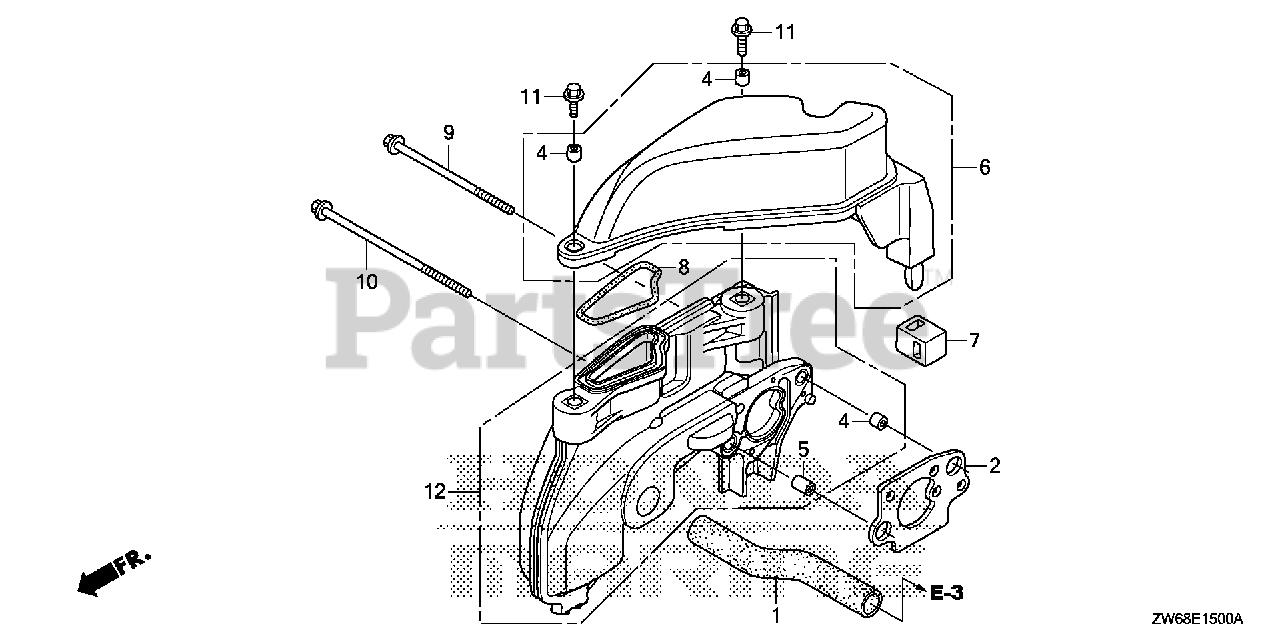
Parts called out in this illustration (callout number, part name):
1	TUBE, BREATHER
2	GASKET, AIR GUIDE
3	GUIDE ASSY., AIR
4	COLLAR, DISTANCE
5	COLLAR, DISTANCE (14MM)
6	CASE, MUFFLER
7	GROMMET, MUFFLER
8	SEAL, MUFFLER
9	BOLT, FLANGE (5X62)
10	BOLT, FLANGE (5X70)
11	BOLT, FLANGE (5X12)
12	GUIDE, AIR INLET
